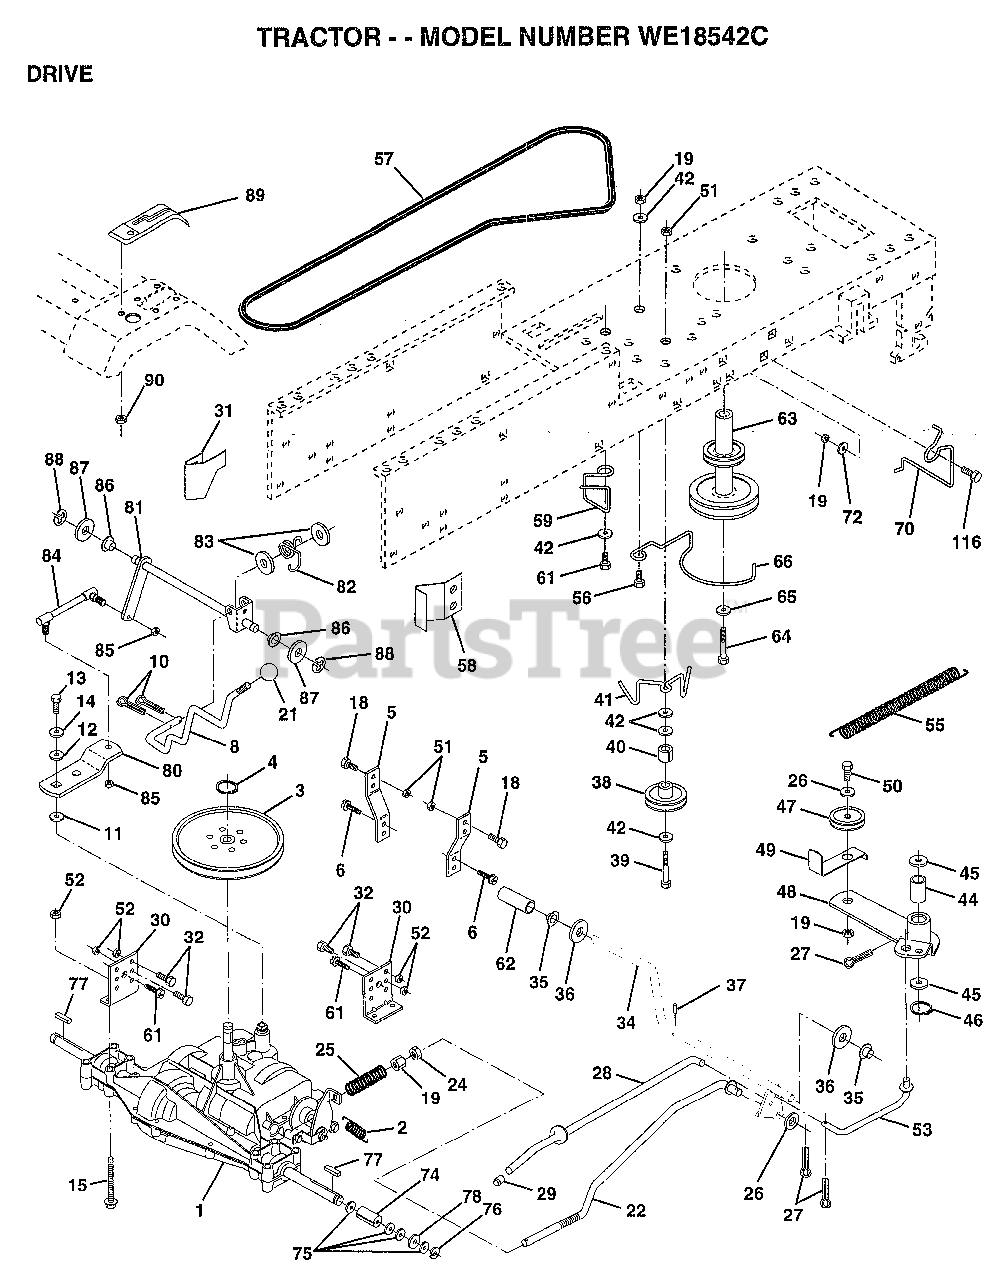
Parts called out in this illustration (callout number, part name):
1	TRANSAXLE ASM
2	SPRING.BRAKE.RETU
3	PULLEY TRANS
6	SCREW
8	ROD SHIFT FEND LT
10	PIN COTTER 1/8
11	WASH-SHFT PLT LT
13	BOLT.1/4-28.W/PAT
14	LOCKWASHER
15	BOLT.HX.FLG.5/16
18	BOLT
19	NUT
21	KNOB T (1/2-HOLE)
22	BRAKE ROD
24	NUT
25	SPRING ROD LT
26	WASHER
27	COTTER PIN
28	ROD.BRAKE.PARK.LT
29	PLUNGER CAP T
30	TRANSAXLE MTG BKT
31	"KEEPER,BELT LH T"
32	BOLT
34	SHAFT ASM-PEDAL F
35	NYLON BEARING
36	WASHER LT
38	PULLEY.IDLER.FLAT
39	BOLT
40	SPACER T
42	WASHER
48	BELLCRANK.CLUTCH
49	RETAIN BELT
52	NUT
53	"LINK, CLUTCH T"
55	"SPRING, RETURN LT"
57	"V-BELT,95.3"
58	"KEEPER,BELT RH T"
59	KEEPER BELT CNTSP
61	SCREW
62	PEDAL COVER T
63	PULLEY.ENGINE
64	BOLT
65	LOCKWASHER
66	KEEPER-BELT
70	KEEPER BELT ENG
72	WASHER
74	SPACER LT
76	E-RING LT
77	SQUARE KEY
78	WASHER
80	ARM.SHIFT.TRANS.
81	SHAFT ASSY CROSS
82	"SPRING,TORSION"
83	WASHER
84	"ROD.TIE.20""P930LT"
85	NUT.CNT.LOCK.1/4
86	BUSHING
87	WASHER D
88	KLIP RING
90	NUT
112	WASHER LT
116	BOLT RDHD 3/8-16
149	SPACER RETAINER
150	BUSHING.NYLON
151	WASHER
